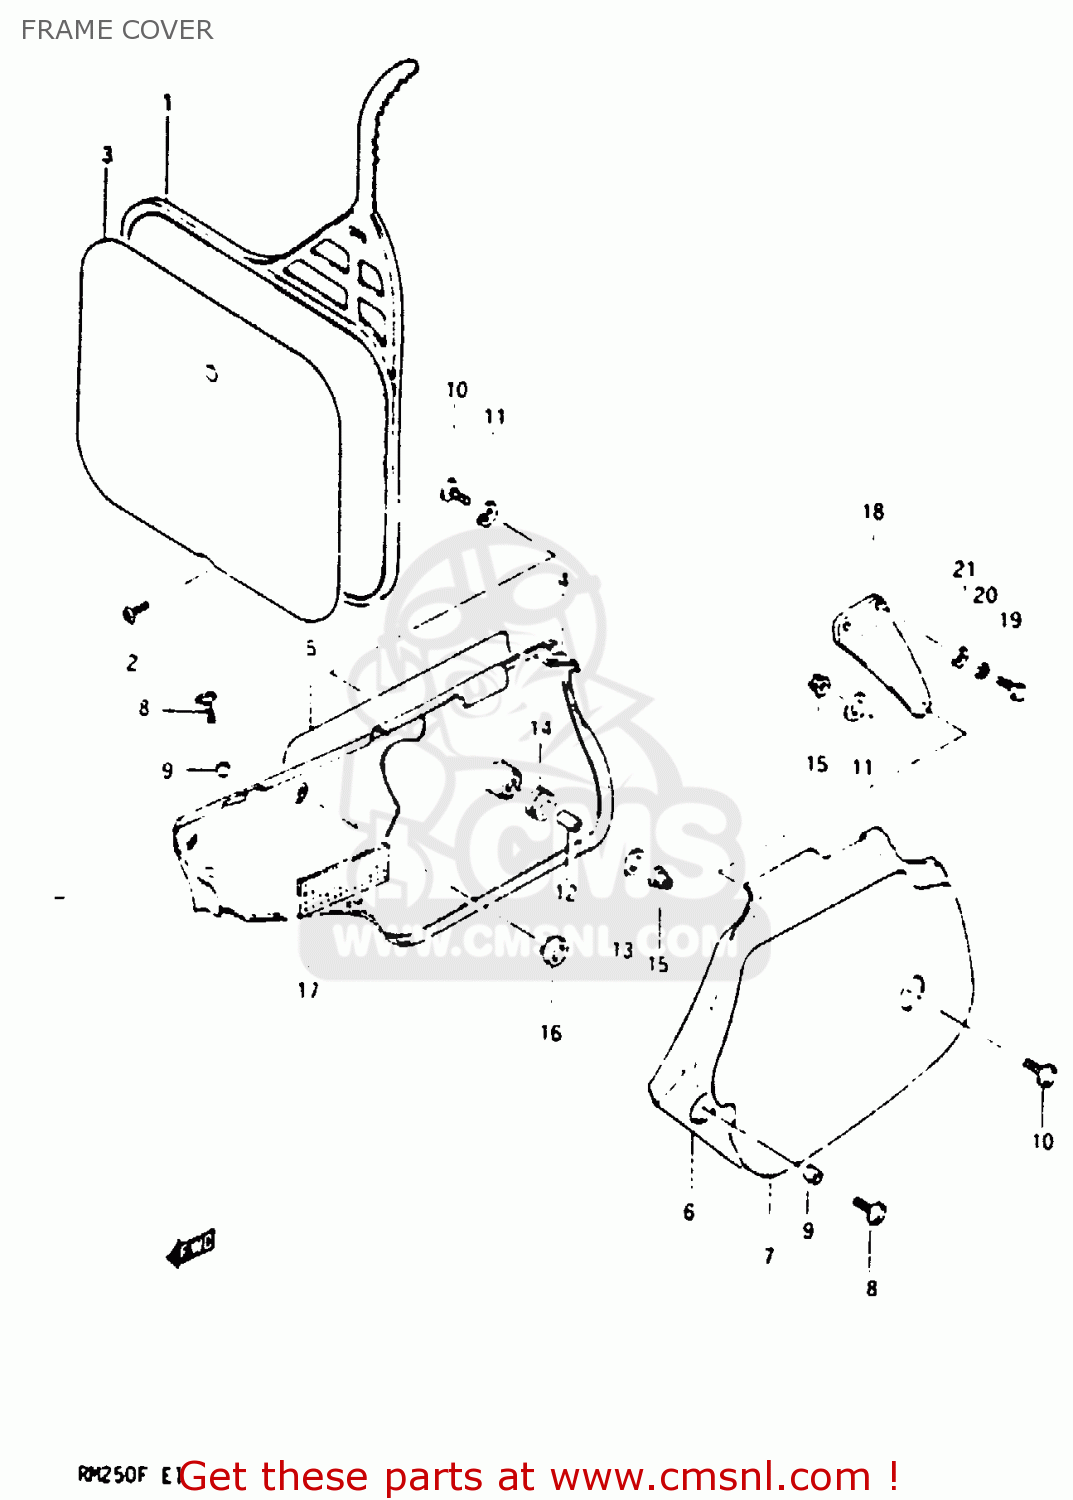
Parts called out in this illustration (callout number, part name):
1	PLATE,NUMBER,FRONT
2	SCREW
3	EMBLEM,FRONT NUMBER PLATE
4	COVER,FRAME,RIGHT
5	EMBLEM
6	COVER,FRAME,LEFT
7	EMBLEM,NUMBER PLATE,LEFT
8	SCREW(6X14)
9	SPACER (6.1X8X3.5)
10	SCREW(6X20)
11	WASHER FRAME COVER
12	SPACER (6.1X9X9)
13	WASHER (6.5X24X1.6)
14	CUSHION
15	NUT 6MM
16	CUSHION
17	HEAT SHIELD,FRAME COVER
18	STAY,FRAME COVER,LEFT
19	BOLT
20	WASHER,LOCK
21	WASHER(6.5X16X1.2)
